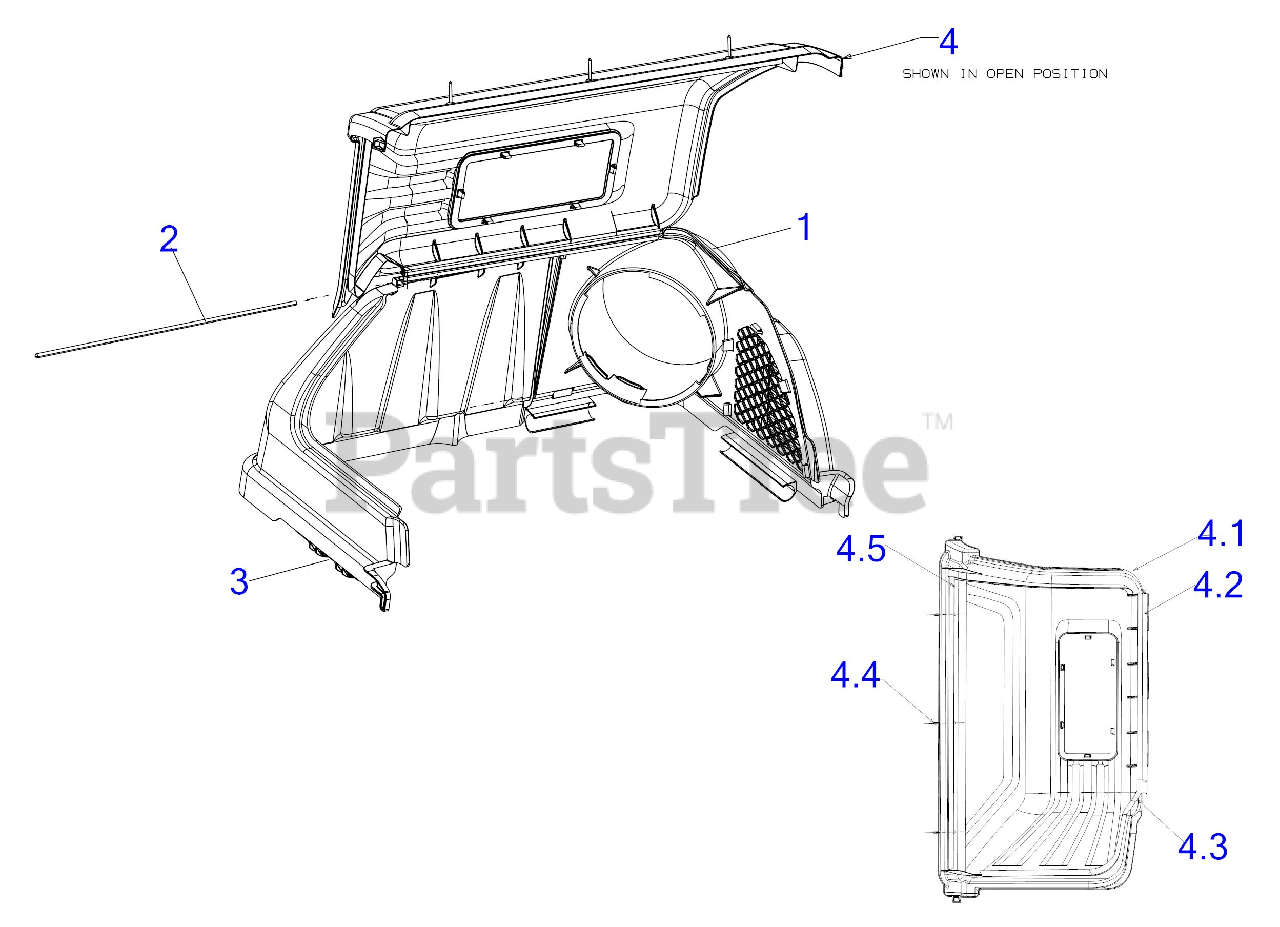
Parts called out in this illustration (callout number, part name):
1	BAGGER VENT WALL ASSEMBLY
2	BAGGER HOOD HINGE PIN
3	BAGGER SUPPORT COVER (LH)
4	COMPLETE BAGGER HOOD
4.1	TWIN BAGGER COVER W/ WINDOW
4.2	TRIM LOCK SEAL 17.4"
4.3	TRIM LOCK SEAL 21.5"
4.4	RIVOT
4.5	STIFFENER BRACKET
